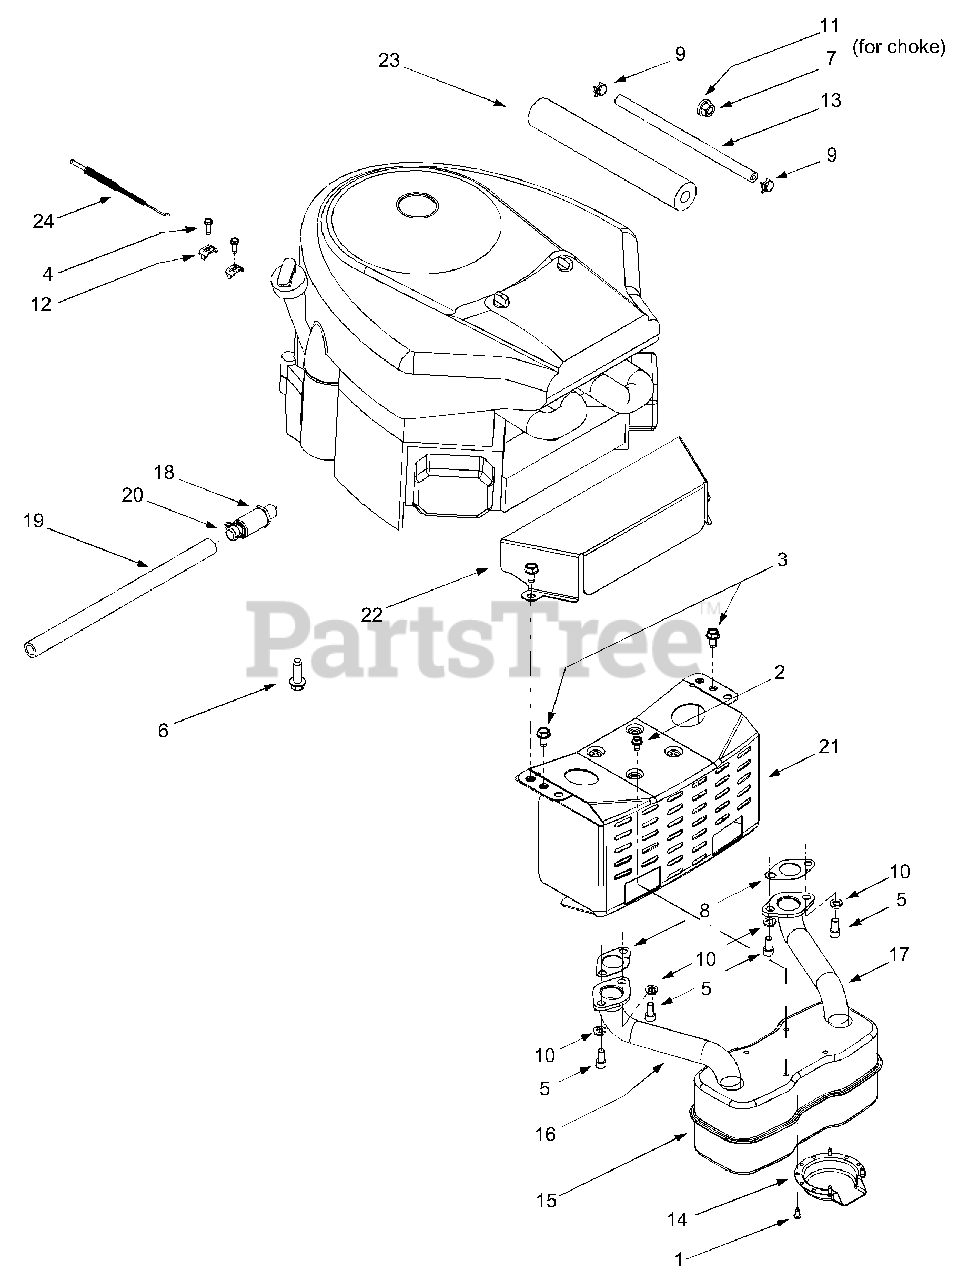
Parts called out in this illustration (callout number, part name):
1	Self-tapping Screw, #8-18 x.5
2	Self-tapping Screw, 1/4-20 x.5
3	Self-tapping Screw, 5/16-12 x.750
4	Screw, #10-32 x.625
5	Socket Cap Screw, 5/16-18 x.625
6	Self-tapping Screw, 3/8-16 x 1.25
7	Hex Nut, 3/8-16
8	Exhaust Gasket
9	Hose Clamp
10	Lock Washer, 5/16
11	Flat Washer
12	Casing Clamp
13	Fuel Line Hose
14	Muffler Deflector
15	Muffler, Twin Inlet
16	RH Exhaust Pipe
17	LH Exhaust Pipe
18	Oil Drain Valve
19	Oil Drain Hose
20	Oil Drain Cap
22	Engine Heat Shield
23	Foam (fits over fuel line)
24	Throttle Cable
